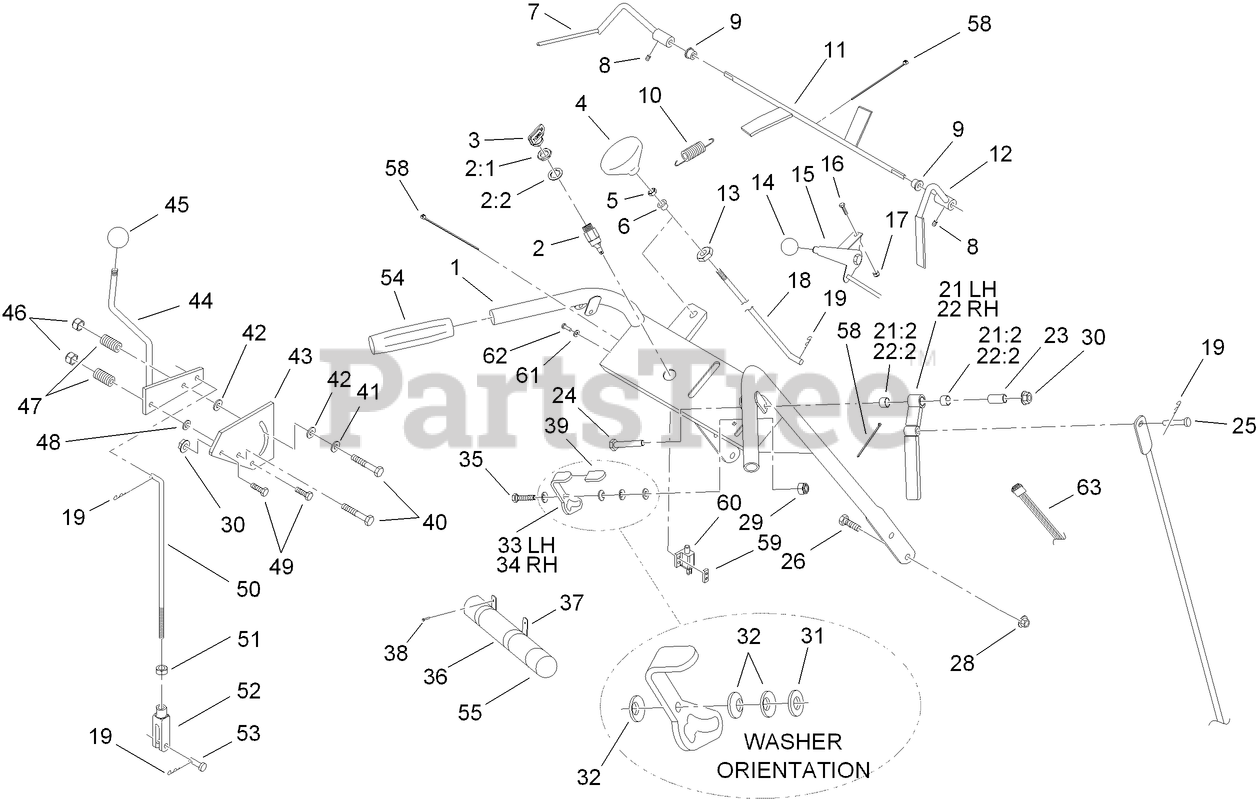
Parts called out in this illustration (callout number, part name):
1	HYDRO HANDLE ASM
2	SWITCH-ON / OFF
2:1	NUT-HH
2:2	WASHER-TOOTH, INTERNAL
3	KEY-IGNITION
4	Knob-Push / Pull
5	NUT-JAM
6	Bearing-Nylon
7	LH OPERATOR PRESENCE CONTROL LEVER ASM
8	SCREW-SET
9	BUSHING-NYLON
10	SPRING-EXTENSION
11	ROD-CONTROL, OPERATOR PRESENCE
12	RH OPERATOR PRESENCE CONTROL LEVER ASM
13	NUT-PUSH
14	KNOB-BALL
15	THROTTLE CABLE ASM
16	BOLT-CARR
17	NUT-LOCK, NI
18	Linkage-Blade
19	PIN-COTTER
21	LH Drive Lever ASM
21:2	BUSHING-SLEEVE
22:2	BUSHING-SLEEVE
23	Bushing-Lever, Drive
24	SCREW-HH
25	Pin-Clevis
26	SCREW-HHF
28	NUT-HF
29	NUT-LOCK, NI
30	NUT-HF
31	WASHER-FLAT
32	WASHER-SPRING
33	LH LATCH GRIP ASM
35	SCREW-HH
36	TUBE-MANUAL
37	CLAMP-R
38	SCREW-HWHTF
39	GRIP-LATCH
40	SCREW-HH
41	Washer-Friction
42	Washer-Friction
43	PLATE-LEVER, SHIFTER
44	LEVER-SHIFT
45	KNOB-BALL
46	NUT-LOCK, NI
47	SPRING-COMPRESSION
48	WASHER-PLAIN
49	SCREW-HH
50	Rod-Control, Speed
51	NUT-JAM
52	YOKE-ADJUSTABLE
53	PIN-CLEVIS
54	GRIP-FOAM
55	CAP-HOUSING
58	TIE-CABLE
59	PLATE-TAPPED
60	SWITCH-OPEN, NORMALLY
61	WASHER-FLAT
62	SCREW-PPH
63	Harness-Wiring
